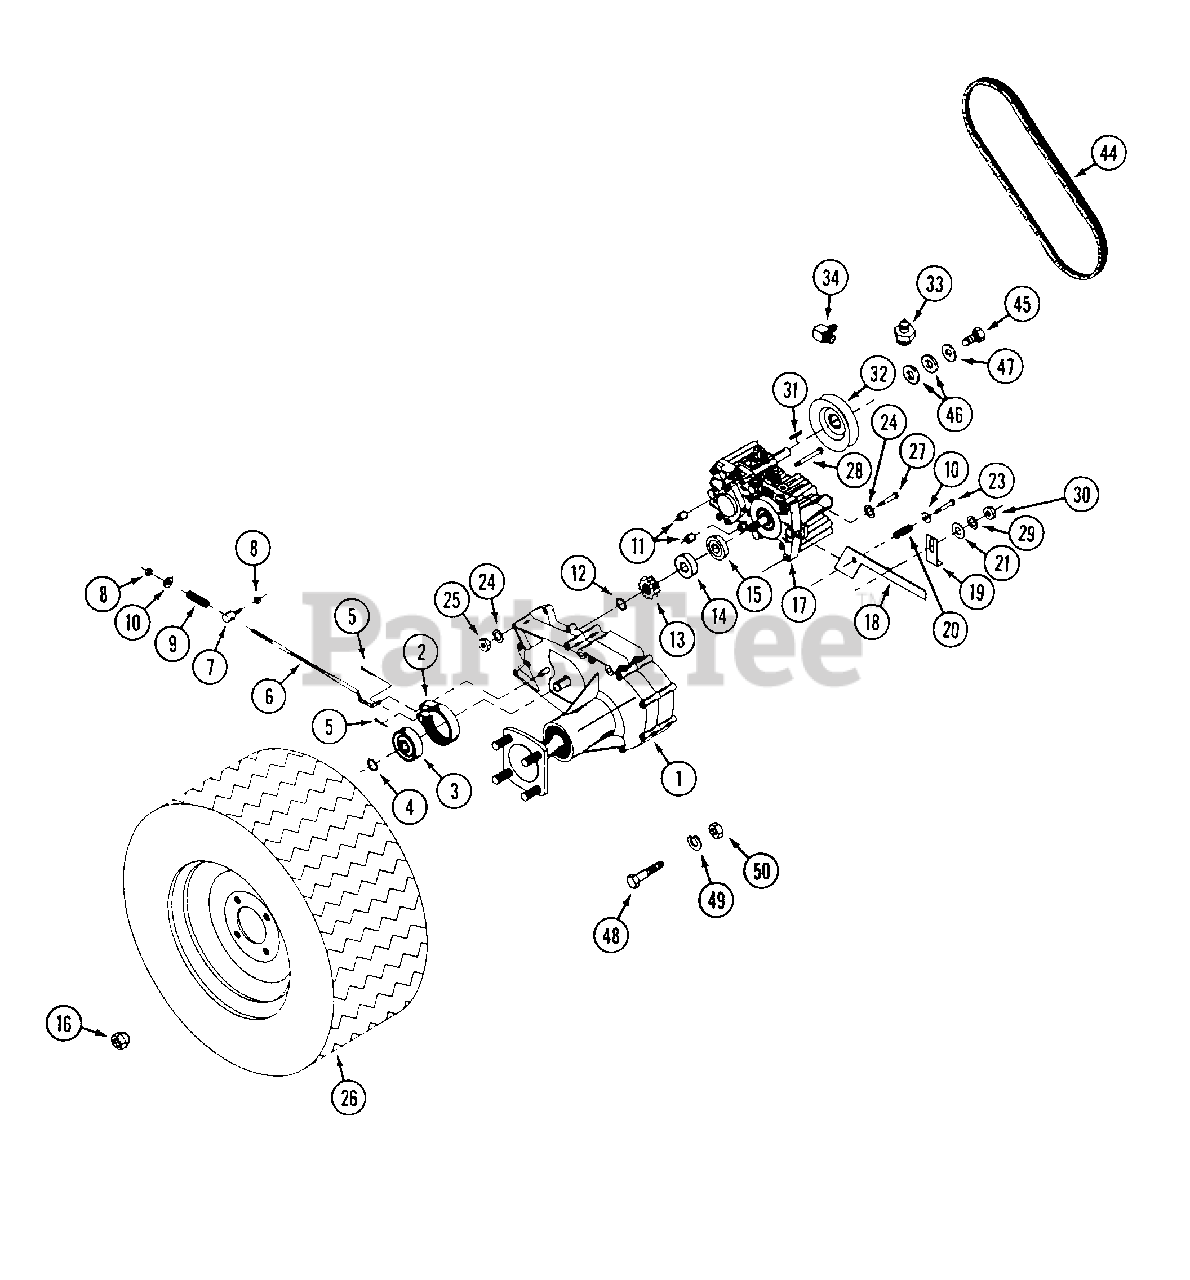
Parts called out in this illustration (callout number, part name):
1	TRANSMISSION - ZT
5	PIN - cotter 1/8" x 1"
7	COLLAR - brake rod
8	NUT - lock 1/4" - 20
10	WASHER - 1/4"
12	RING - snap
14	BEARING
16	NUT - lug 1/2" - 20
17	PUMP - hydro R.H.
18	LEVER - transmission dump R.H.
19	BRACKET - dump lever stop
20	SPRING - compression
21	WASHER - 3/8"
23	BOLT - dump valve
24	LOCKWASHER - 5/16"
25	NUT - 5/16" - 18
26	WHEEL ASSEMBLY
27	BOLT - 5/16" - 18 x 1-3/4"
28	BOLT - 5/16" - 18 x 7-1/2"
29	LOCKWASHER - 3/8"
30	NUT - 3/8" - 16
31	KEY-5 x 5 x 25 mm
32	PULLEY - 4" O.D. x 15 mm ID
33	ADAPTER
34	ADAPTER - 90°
44	BELT - pump drive
45	BOLT - M6 - 1.0 x 12m flange
46	WASHER - .625" x 1"
47	WASHER - .312" x .875"
48	BOLT - 3/8" - 16 x 3-1/2" mounting
49	LOCKWASHER - 3/8"
50	NUT - 3/8" - 16
